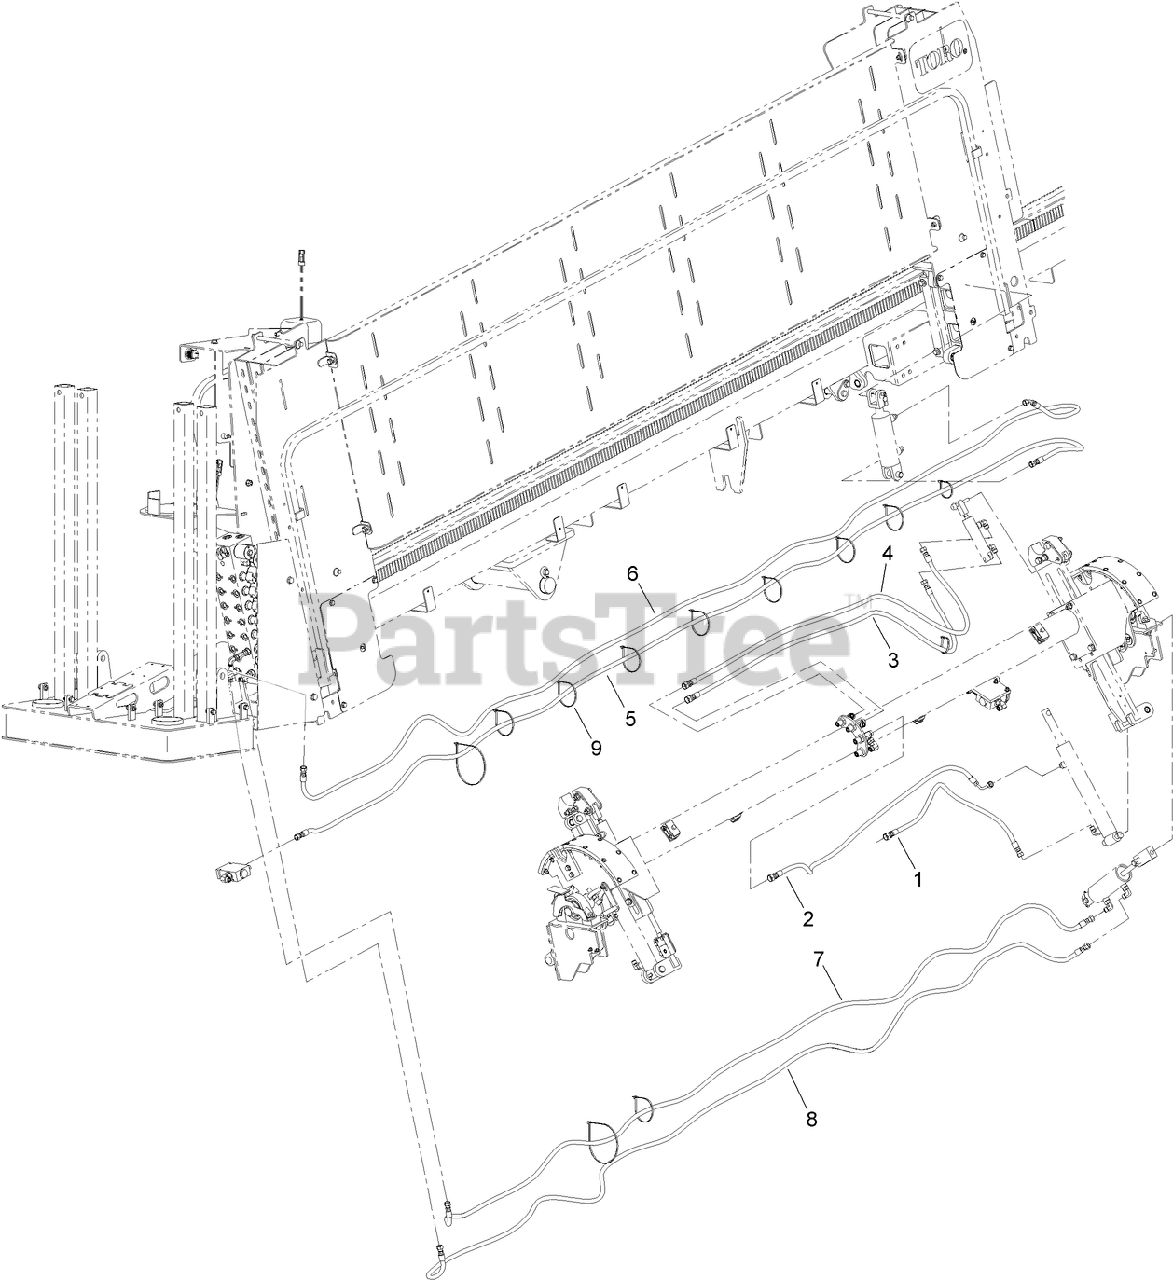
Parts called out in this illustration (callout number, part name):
1	HOSE ASM
2	HOSE ASM
3	HOSE ASM
4	HOSE ASM
5	HOSE ASM
6	HOSE ASM
7	HOSE ASM
8	HOSE ASM
9	TIE-CABLE
